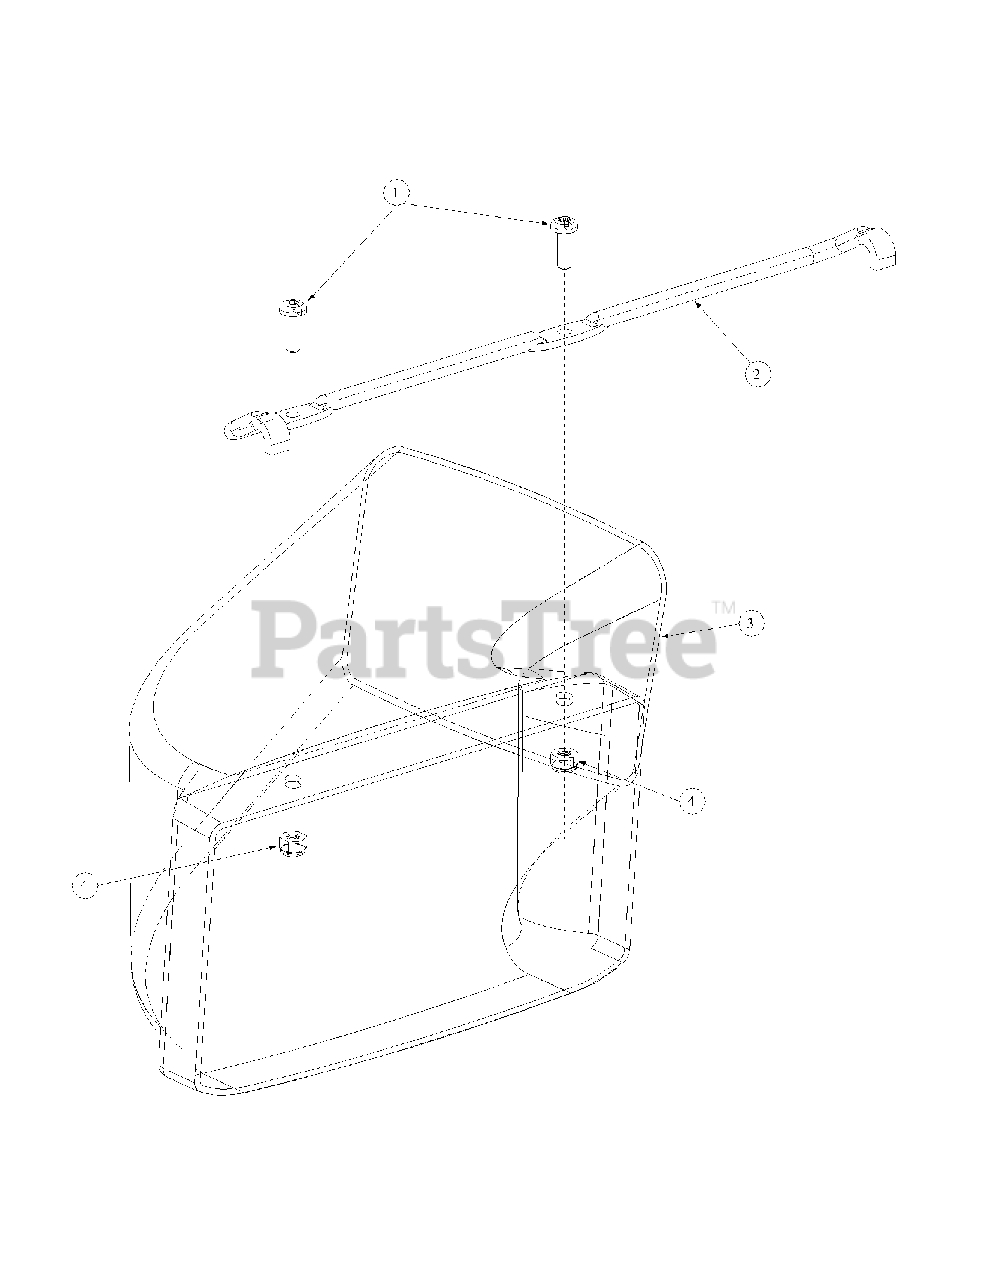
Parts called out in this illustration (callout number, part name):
1	Machine Screw, 1/4-20, .750, PANTRXI
2	21" Side Chute Mounting Rod
3	21" Side Chute Spiral Deck
4	Hex Nut 1/4-20, GRC, Lock
